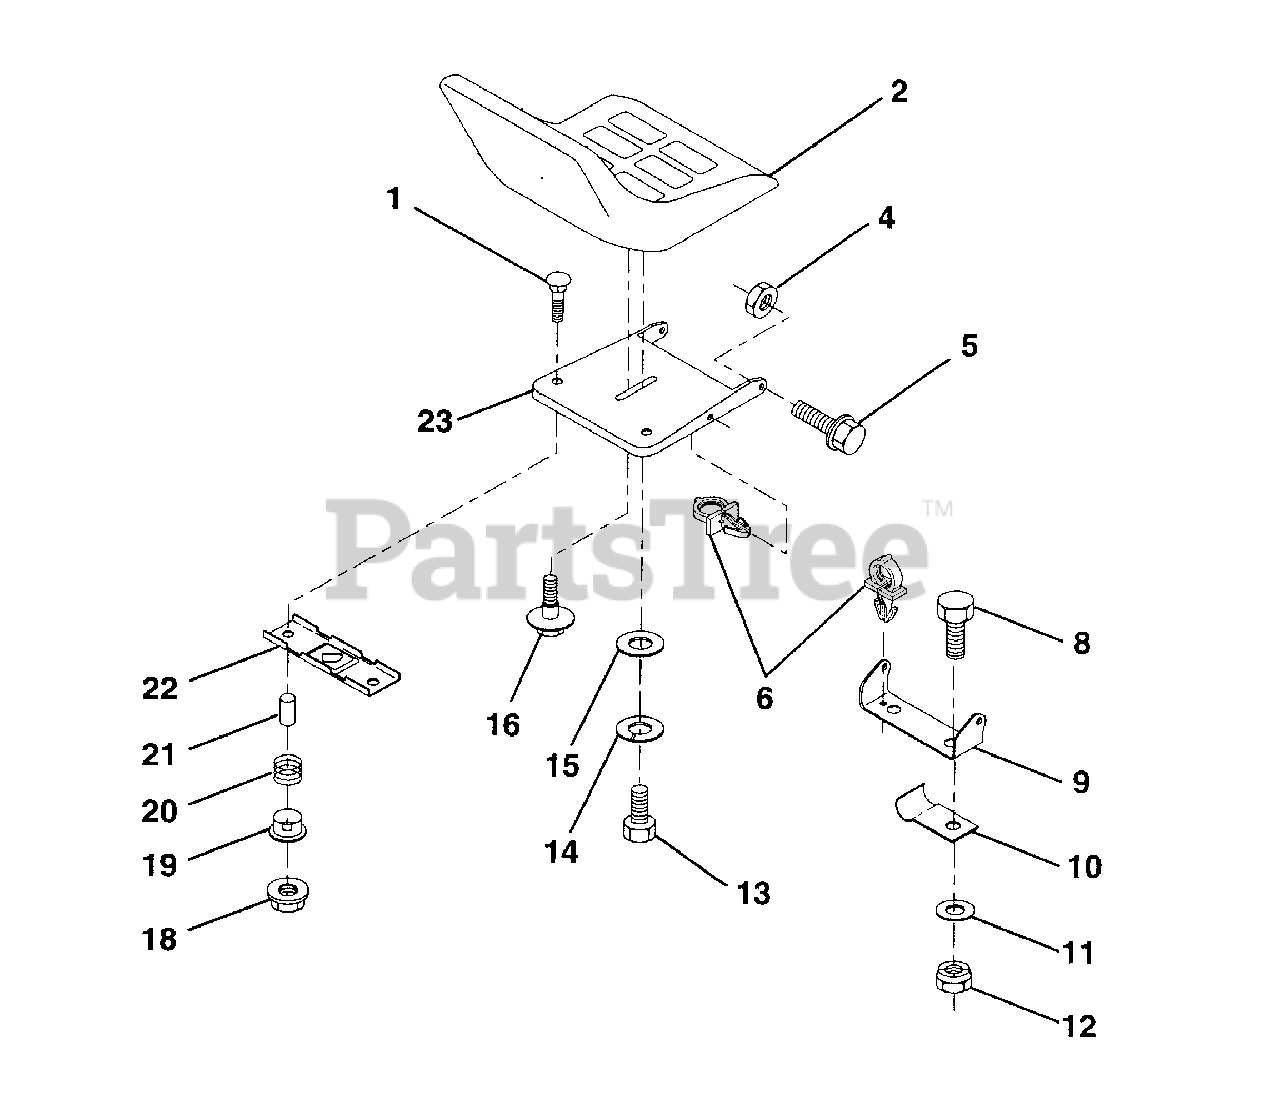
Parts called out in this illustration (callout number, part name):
1	Bolt, Carriage 1/4-20 x 1-3/8
2	Seat
4	Nut, Crownlock 5/16-18
5	Bolt, Shoulder 5/16-18 UNC
6	Clip, Insulated
8	Bolt, Fin Hex 3/8-16 UNC x 3/4
9	Bracket, Pivot Seat
10	Clip, Insulated
11	Washer 12/32 x 2 x 10 Ga.
12	Nut, Crownlock 3/8-16 UNC
13	Bolt Hex 1/2-13 x 7/8
14	Washer Lock Hvy. Hlicl Spring 1/2
15	Washer, 17/32 x 1-3/16 x 12 Ga.
16	Bolt, Shoulder
18	Nut, Hex Large Flange Lock
19	Bushing, Snap
20	Spring, Compression
21	Spacer, Split 28 Id. x .88 Lg.
22	Bracket, Switch, Mounting
23	Pan, Seat
